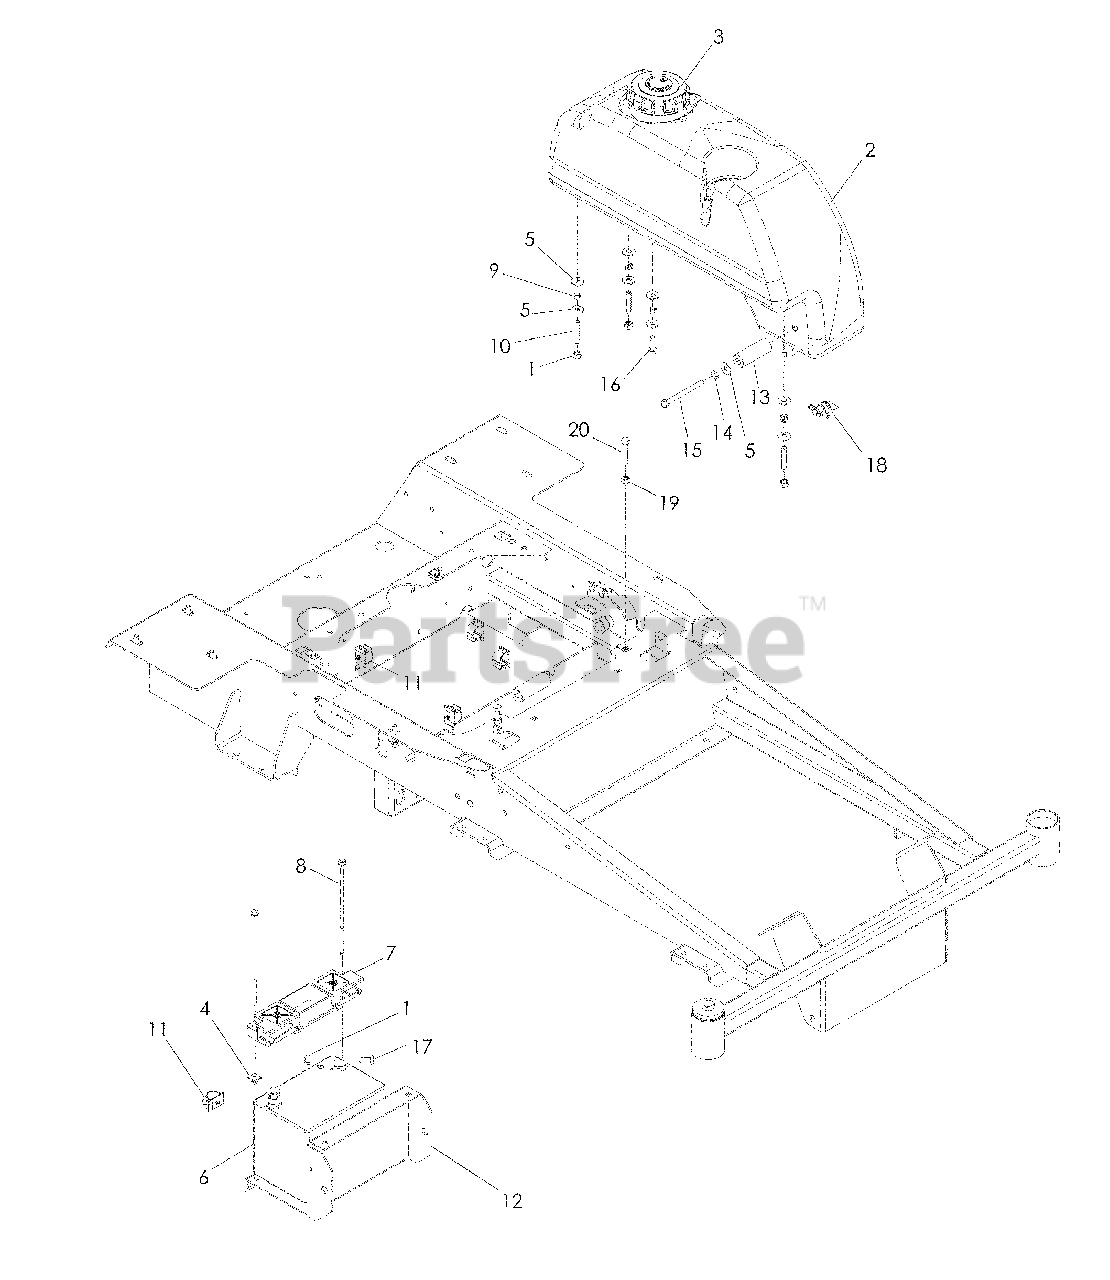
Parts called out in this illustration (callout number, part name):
1	NUT 5/16-18 NYLOC
2	FUEL TANK, LEFT
3	FUEL CAP
4	PUSH NUT NYLON
5	WASHER 5/16
6	BATTERY
7	BATTERY HOLD DOWN
8	BOLT, ¼ x 7½
9	SPRING, TANK MOUNT
10	TANK STUD, FUEL 5/16C
11	PUSH MOUNT, WIRE CLIP
12	BATTERY TRAY
13	TANK SPACER
14	LOCKWASHER 5/16
15	HCS 5/16-18 x 3½
16	HCS 5/16-18 x 1
17	HCS 5/16-18 x ¾
18	FUEL VALVE
19	NUT 5/16-18
20	HCS 5/16-18 x 1¾ TPBL
